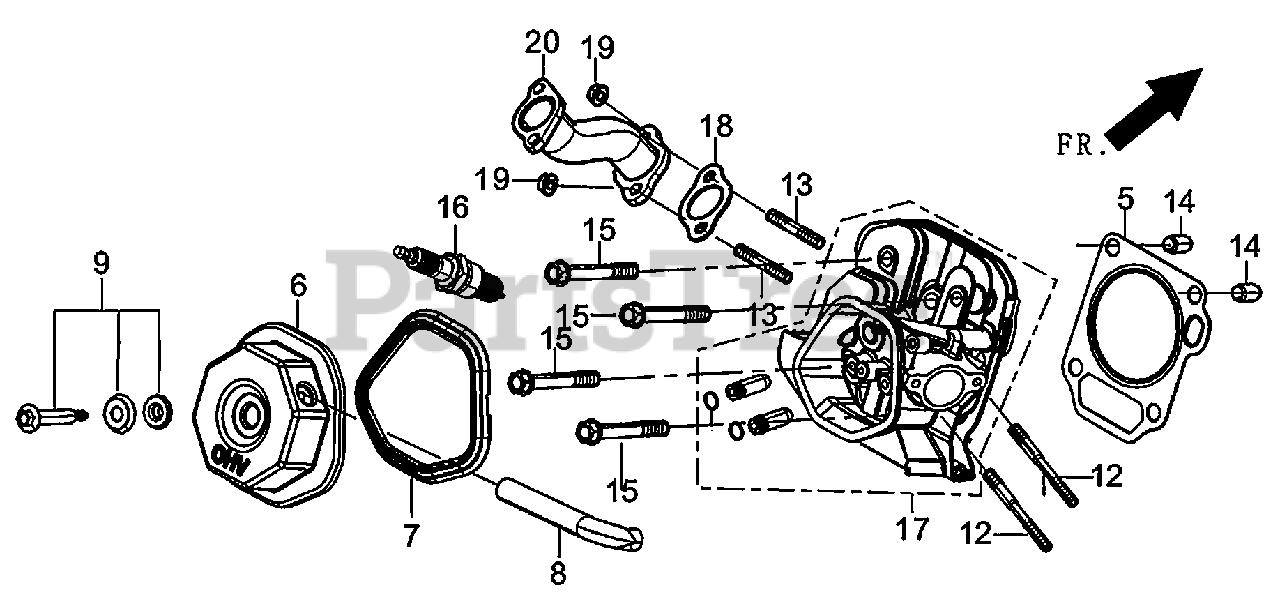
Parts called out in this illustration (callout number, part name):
5	GASKET, CYLINDER HEAD
6	COVER ASSY, CYLINDER HEAD
7	GASKET, CYLINDER HEAD COVER
8	TUBE, BREATHER
9	BOLT ASSY, CYLINDER HEAD COVER
14	PIN, DOWEL
15	BOLT, CYLINDER HEAD
16	PLUG, SPARK
17	HEAD ASSY, CYLINDER
18	GASKET, EXHAUST OUTLET
20	PIPE, EXHAUST, GP 2011
